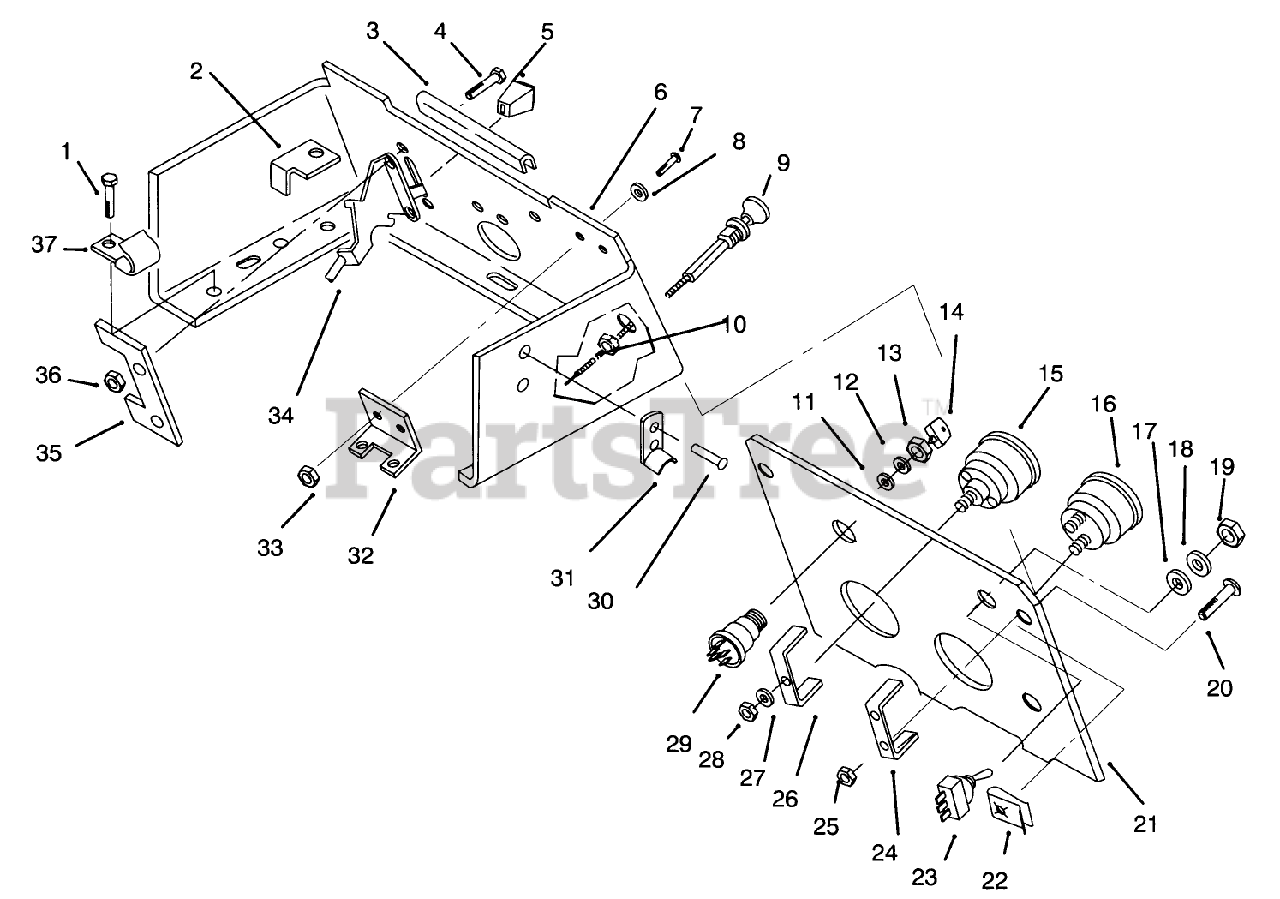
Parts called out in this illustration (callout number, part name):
1	SCREW
2	STOP-PTO
3	EDGING-CONSOLE
7	SCREW
9	CONTROL CHOKE
10	NUT-HEX PALNUT
14	KEY-IGNITION
16	VOLTMETER
17	Washer
18	TAB-WASHER
19	*DISC**
22	CLIP
23	SWITCH-LIGHTS
24	CLAMP-MOUNTING
25	HEX NUT 10-32 E.S. + + USE 3296-21 + +
26	CLAMP-HOUR METER
28	NUT-HEX
29	KEY SWITCH ASM
31	KEEPER-LATCH
32	BRACKET
34	CONTROL-THROTTLE
35	Washer
37	J-CLIP
